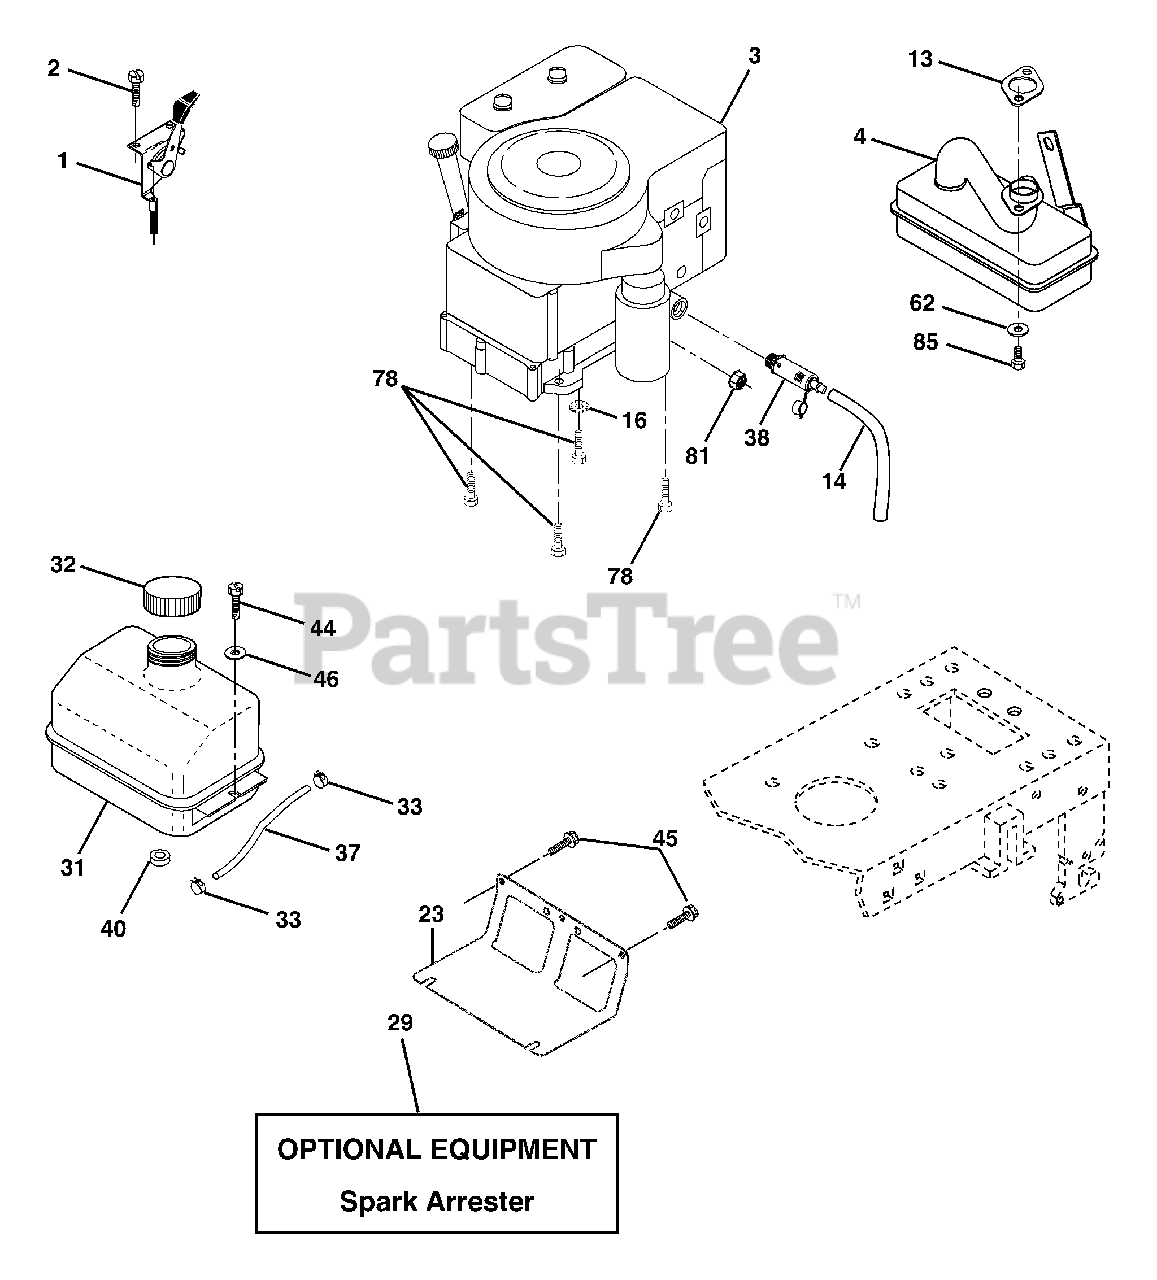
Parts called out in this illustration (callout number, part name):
1	Control Throt /Ch Flag
2	Screw Hex Thd Cut 1/4-20x1/2
4	Muffler
13	Gasket Muffler Tec
14	Tube Drain Oil Easy
16	Washer Lock Ext Tooth 3/8
23	Shield Browning/Debris Guard
29	Arrestor Spark
31	Tank Fuel
32	Cap Asm Fuel W/sym Vented
33	Clamp Hose Blk
37	Line Fuel 20"
38	Plug Drain Oil Easy
40	Bushing
44	Screw Hexwsh Thdrol 1/4-20x3/4
45	Screw Hex Wsh Thdrol 3/8-16
46	Washer 9/32 X 7/8 X 16ga
62	Washer Lock 5/16
78	Screw 3/8-16 x 1-1/4
81	Nut Keps Hex 1/4-20 Unc
85	Bolt Hex HD Phillips
